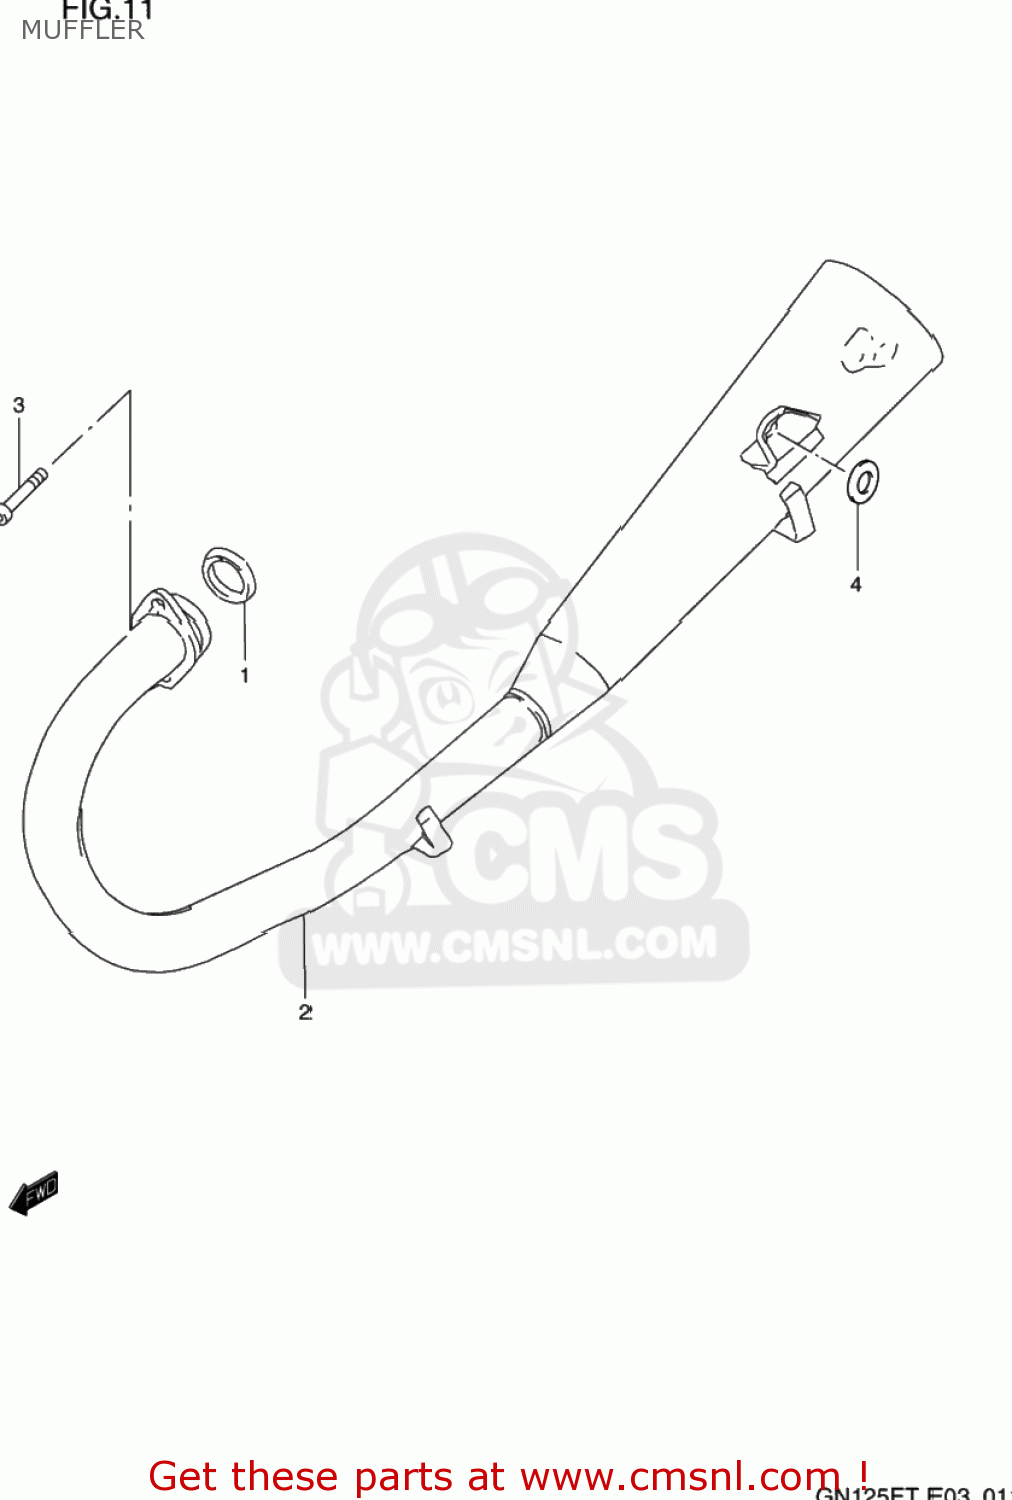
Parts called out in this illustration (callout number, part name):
1	GASKET,EXHAUST (NAS)
2	MUFFLER ASSEMBLY
3	BOLT
4	WASHER
